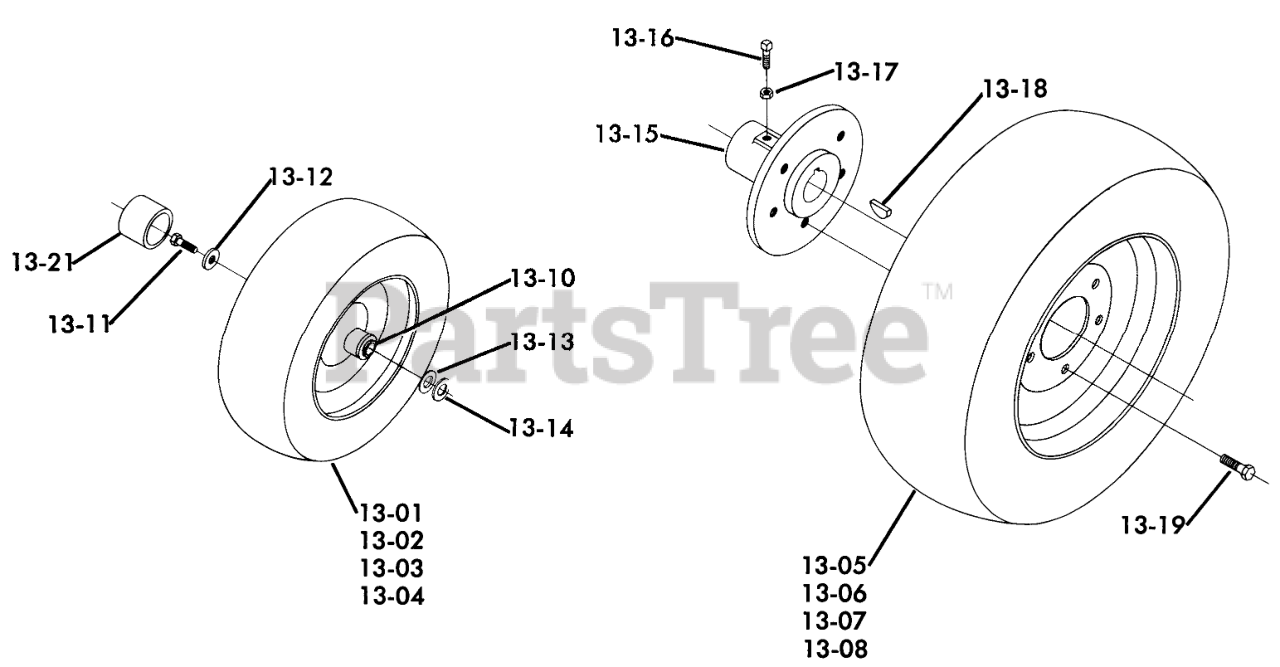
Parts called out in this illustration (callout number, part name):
13-01	Wheel-Complete
13-02	WHEEL
13-03	TIRE TURF SAVER 16X6.50-8
13-04	Tube
13-05	Wheel and Tire
13-05	Wheel & Tire Assembly
13-06	Wheel
13-07	Tire
13-07	Tire-Cleat, Rear
13-08	TUBE-INNER
13-09	VALVE
13-10	Bearing
13-11	Bolt
13-12	WASHER
13-13	WASHER
13-14	WASHER-SHIM
13-15	Hub Rear
13-16	Screw-Set
13-17	Nut
13-18	WOODRUFF KEY
13-19	Lug Nut
13-21	HUB CAP
